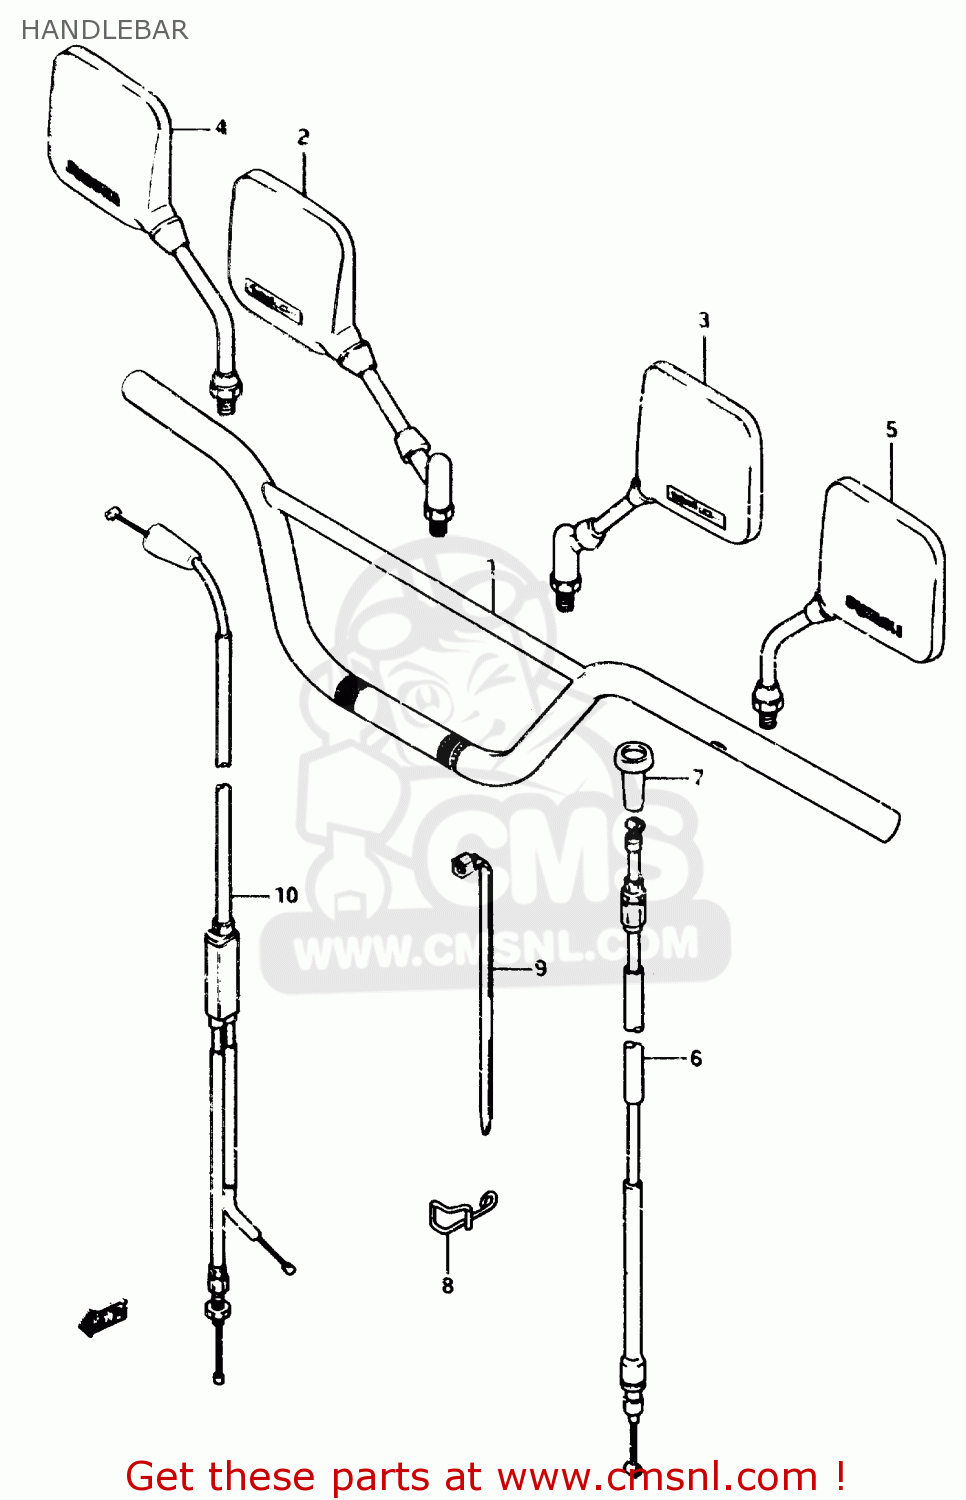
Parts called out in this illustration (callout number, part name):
1	HANDLEBAR
2	MIRROR ASSY, R
3	MIRROR ASSY,L
4	MIRROR, REAR VIEW RH
5	MIRROR, REAR VIEW LH
6	CABLE,CLUTCH
7	BOOT,CLUTCH CABLE
8	GUIDE,CLUTCH CABLE
9	CLAMP(L:235)
10	CABLE ASSY,THROTTLE
